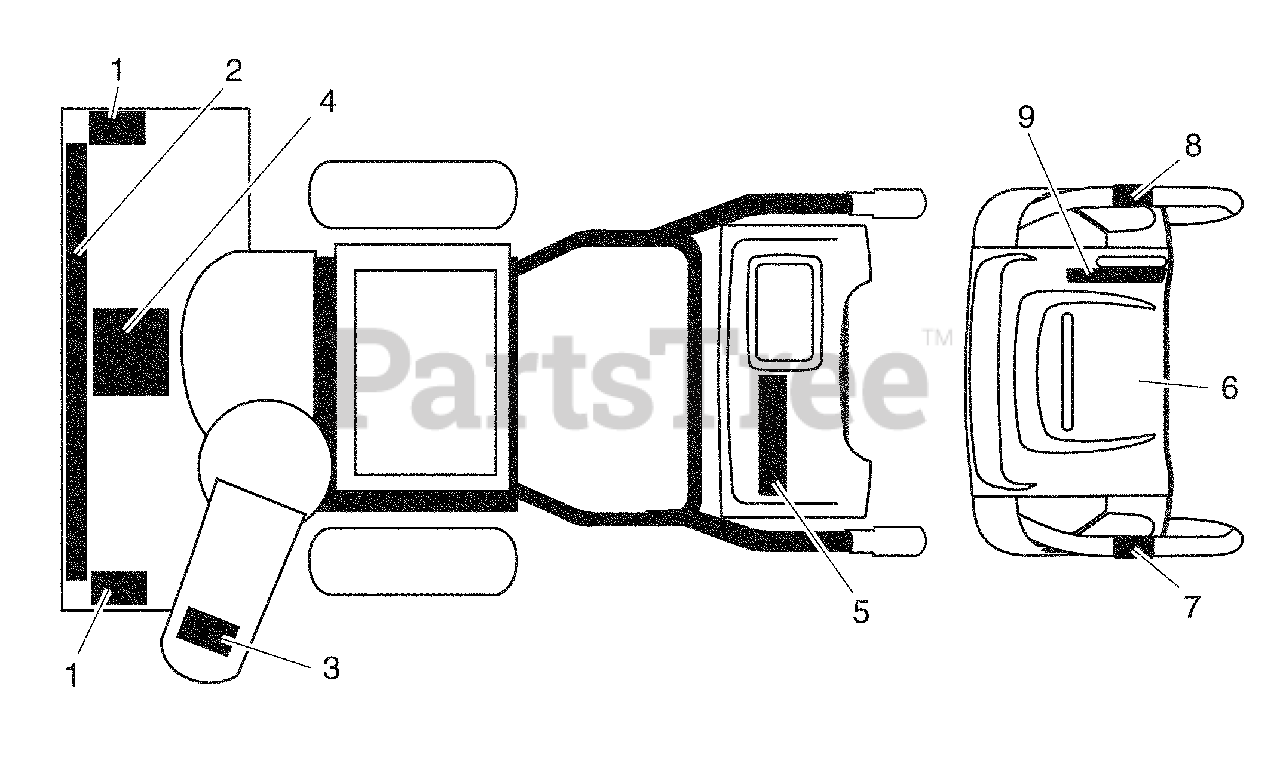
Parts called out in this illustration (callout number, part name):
1	DECAL, DANGER
2	DECAL, HUSQ USA
3	DECAL, DANGER, DEFLECTOR
4	DECAL, DANGER
5	DECAL, HUSQ USA
6	DECAL, INSTRUCTION
7	DECAL, TRACTION LEVER
8	DECAL, AUGER LEVER
9	DECAL, SPEED CONTROL
